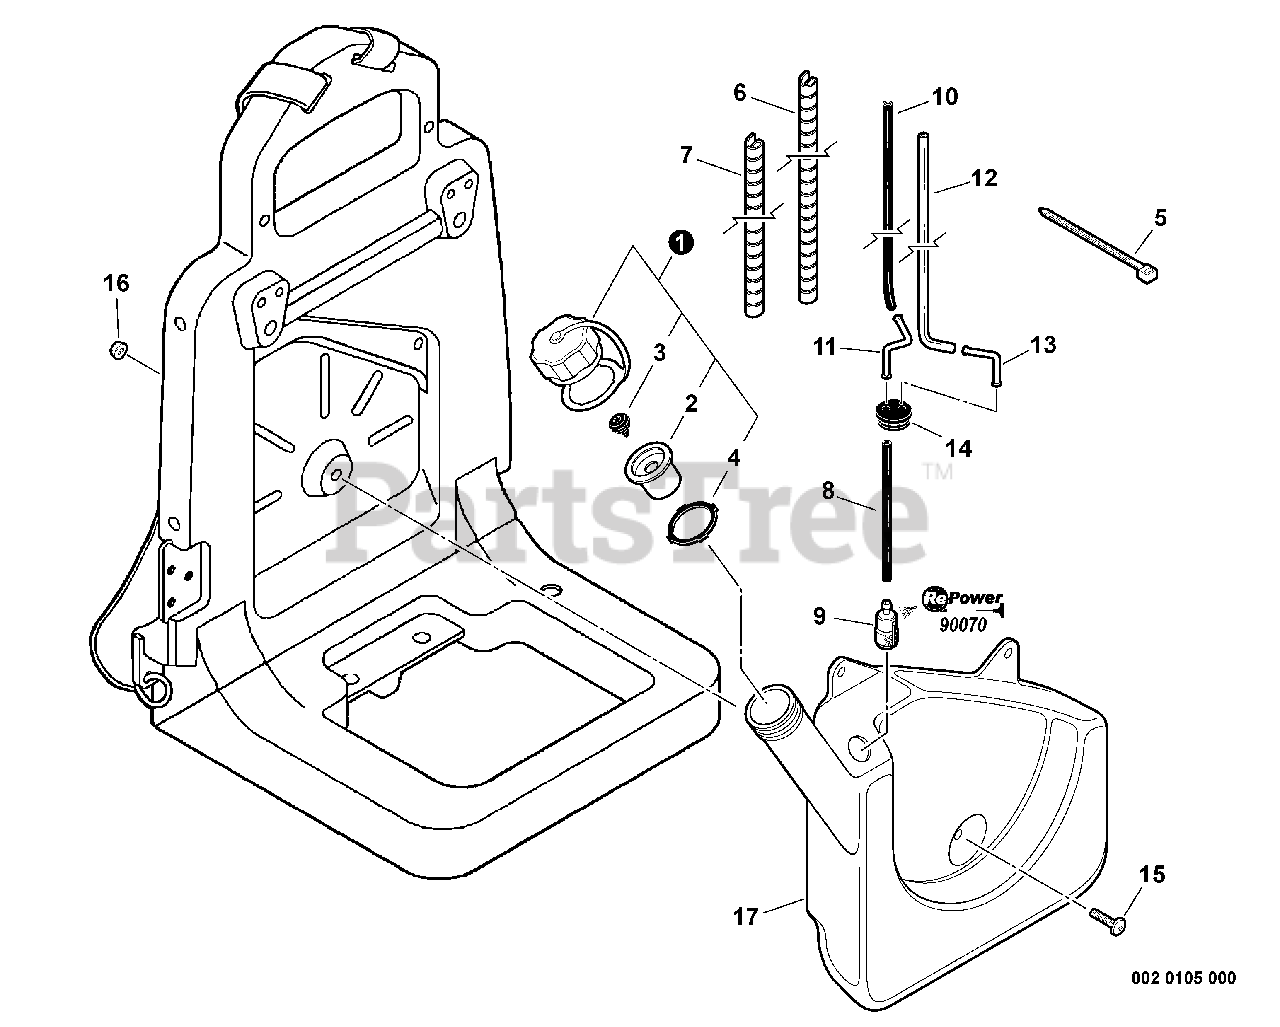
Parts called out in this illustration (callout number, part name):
1	CAP ASSY
2	HOLDER, VENT
4	GASKET, CAP
5	TIE, CABLE
6	WRAP, SPIRAL
7	WRAP, SPIRAL - 130mm
8	PIPE - 3X6X280 -- BLACK
9	FILTER, FUEL
10	PIPE - 3X7X520 -- BLACK
11	CONNECTOR, PIPE
12	PIPE - 2X4X480 -- CLEAR
13	CONNECTOR, PIPE
14	GROMMET
15	SCREW - 5X20
16	LOCKNUT - 5
17	TANK, FUEL
18	RePower TUNE-UP KIT
